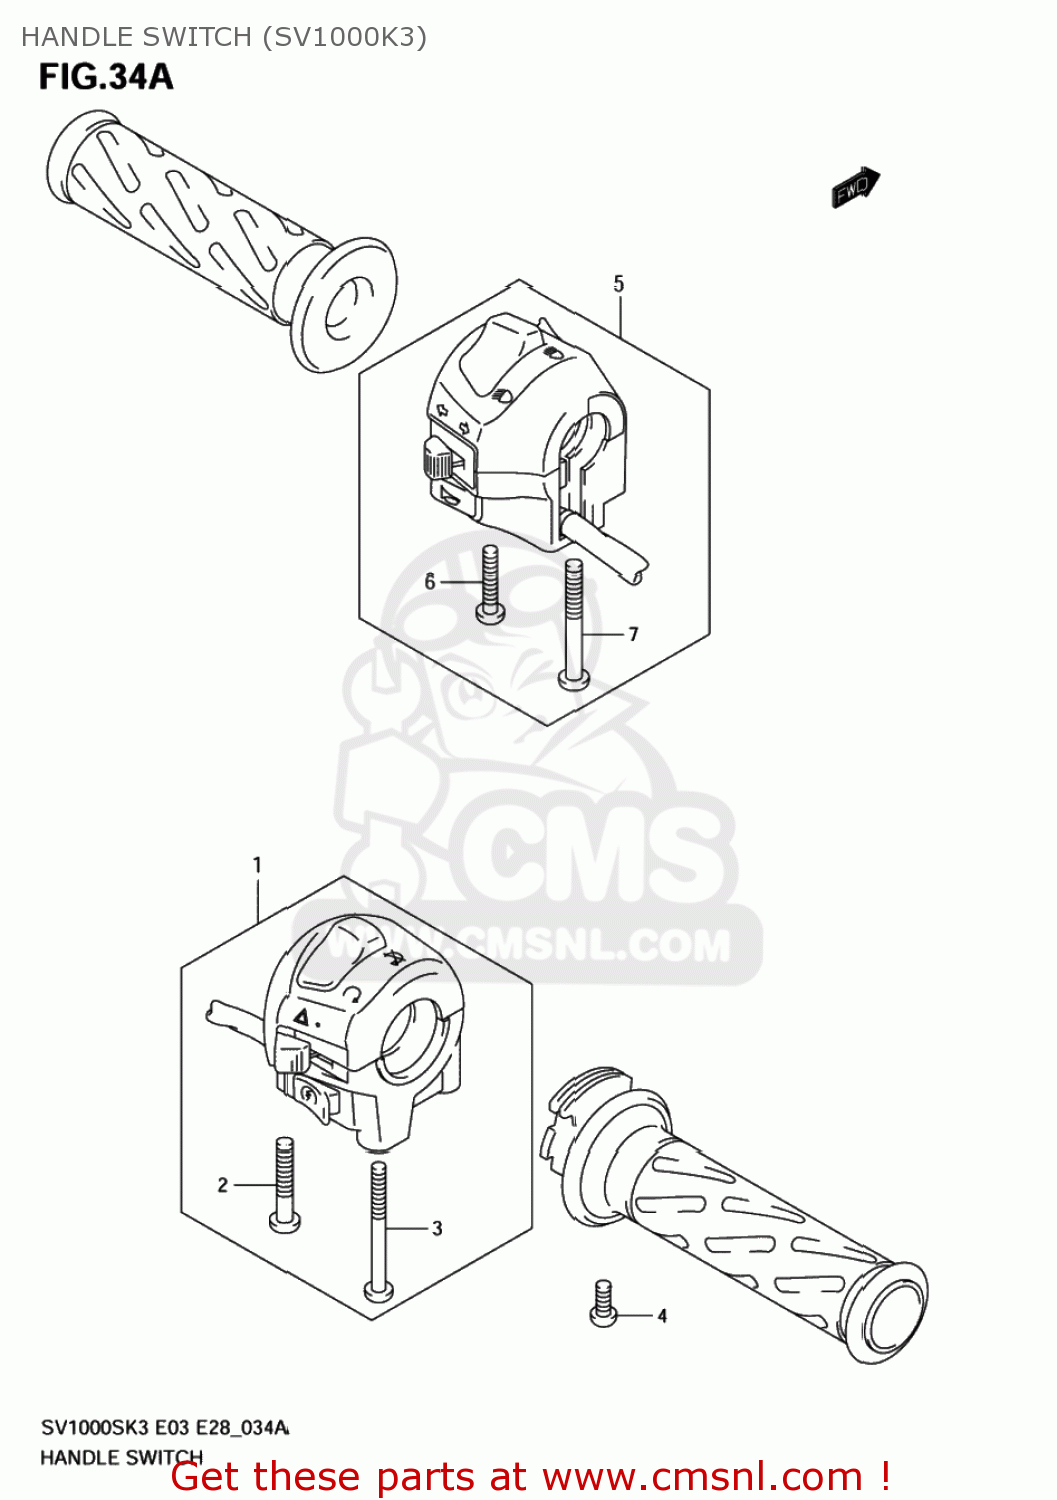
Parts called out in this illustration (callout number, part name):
1	SWITCH ASSY,HANDLE,R
2	SCREW
3	SCREW
4	SCREW
5	SWITCH ASSY,HANDLE,L
6	SCREW
7	SCREW
